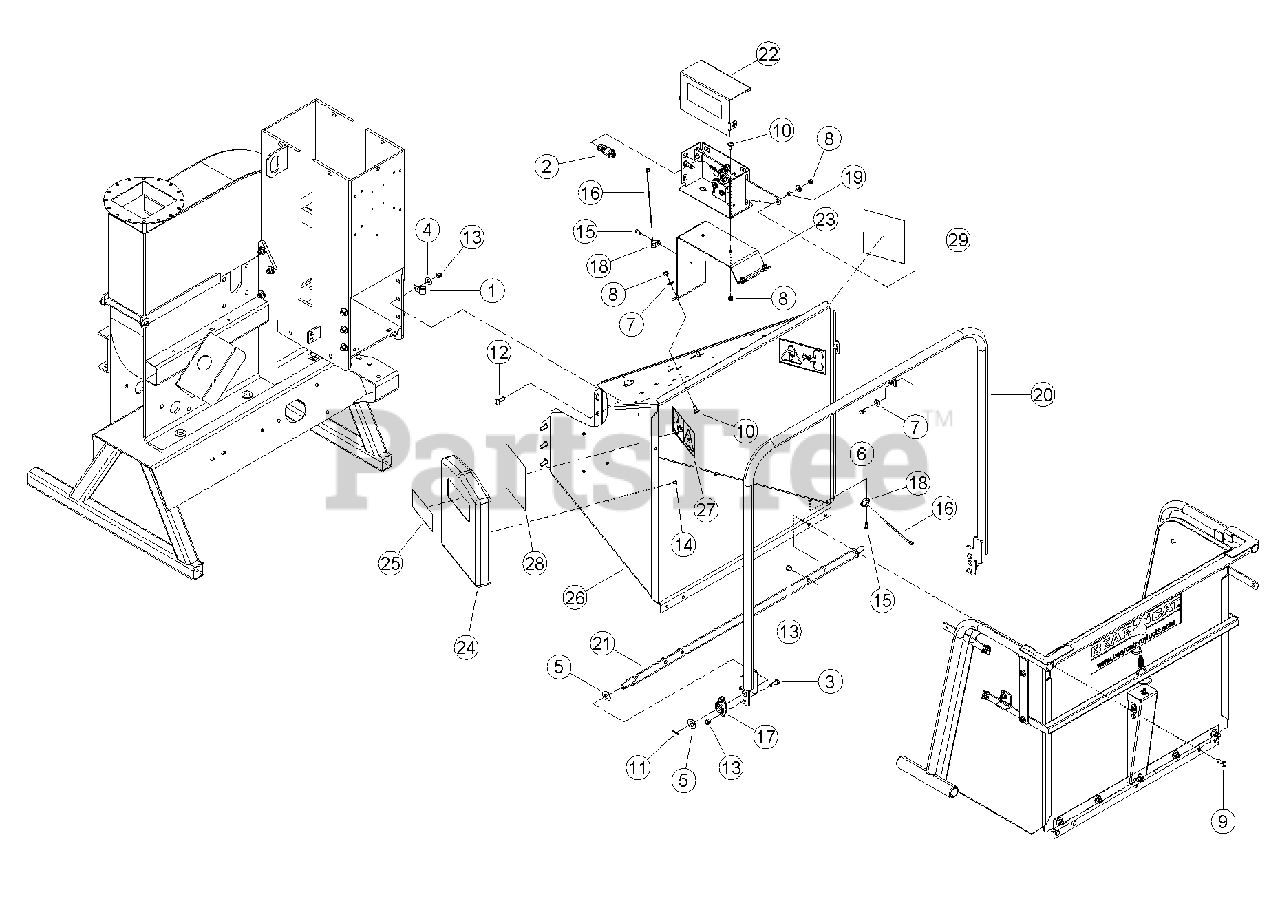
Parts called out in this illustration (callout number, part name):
1	CLAMP, 9/16 COATED
2	SWITCH, N/O MOMENTARY PUSHBUTTON
2	SWITCH, MOMENTARY IP65
3	BOLT, 3/8 X 1 HEX HD GR5 ZP
4	WASHER, 3/8 FLAT ZP
5	WASHER, 5/8 SAE FLAT ZP
6	BOLT, 5/16 X 1 HEX HD GR5 NC ZP
7	WASHER, 5/16 FLAT ZP
8	NUT, 5/16 NE NYLOCK ZP
9	BOLT, 3/8 X 1-1/4 HEX HD GR5 ZP
10	BOLT, 5/16 X 3/4 CRG GR5 NC ZP
11	PIN, 1/8 X 1.00 ZP COTTER
12	BOLT, 3/8 X 1-1/4 CRG GR5 NC ZP
13	NUT, 3/8 NE NYLOCK ZP
14	RIVET, AL BLIND 1/4 X 1/2 DOME HEAD
15	RIVET, AL BLIND 1/4 X 3/4 DOME HEAD
16	STRAP, 11 IN. BLACK TIE
17	BEARING, SIDE FLANGE MOUNT 5/8"
18	CLAMP, CABLE MOUNT
19	SPACER, IDLER PIVOT
20	WELDMENT, CONTROL ARM
21	WELDMENT, CONTROL PIVOT
22	ASSEMBLY, SWITCH BOX
23	MOUNT, SWITCH BOX
24	ASSEMBLY, MANUAL CONTAINER SERVICE PART
25	DECAL, MUTILINGUAL MANUAL
26	ASSEMBLY, BIG CHIPPER CHUTE SERVICE PART
27	DECAL, BLADE DANGER ISO
28	DECAL, FEED POSITION
29	DECAL, FEED POSITION
